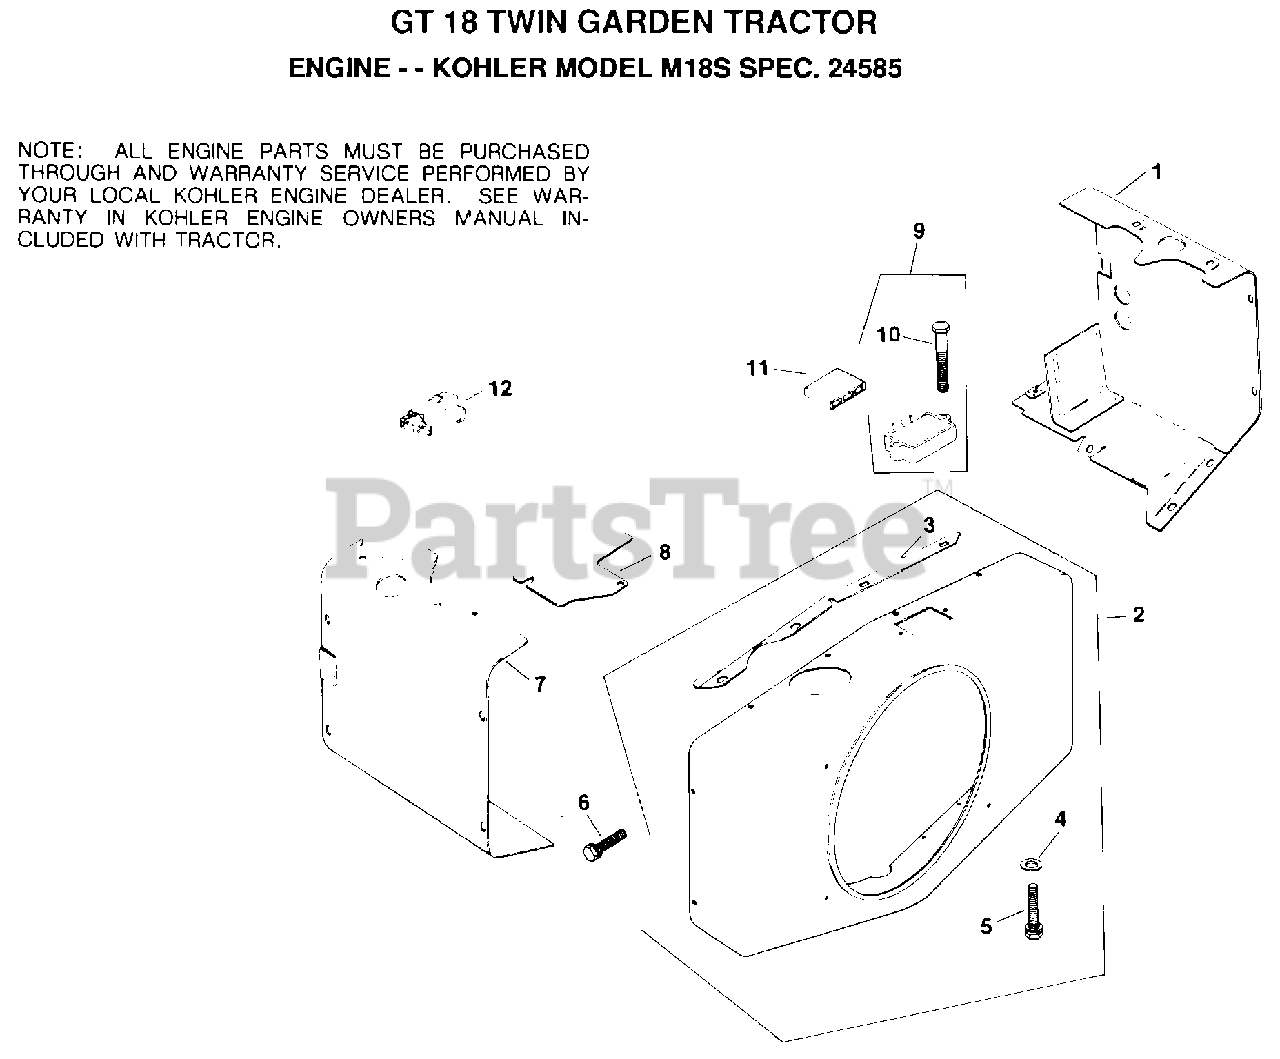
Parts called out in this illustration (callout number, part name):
1	BAFFLE, #1 HEAD
2	KIT, BLOWER HOUSING
7	BATTLE, #2 CYLINDER HEAD
8	BAFFLE, #2 CYLINDER TOP
